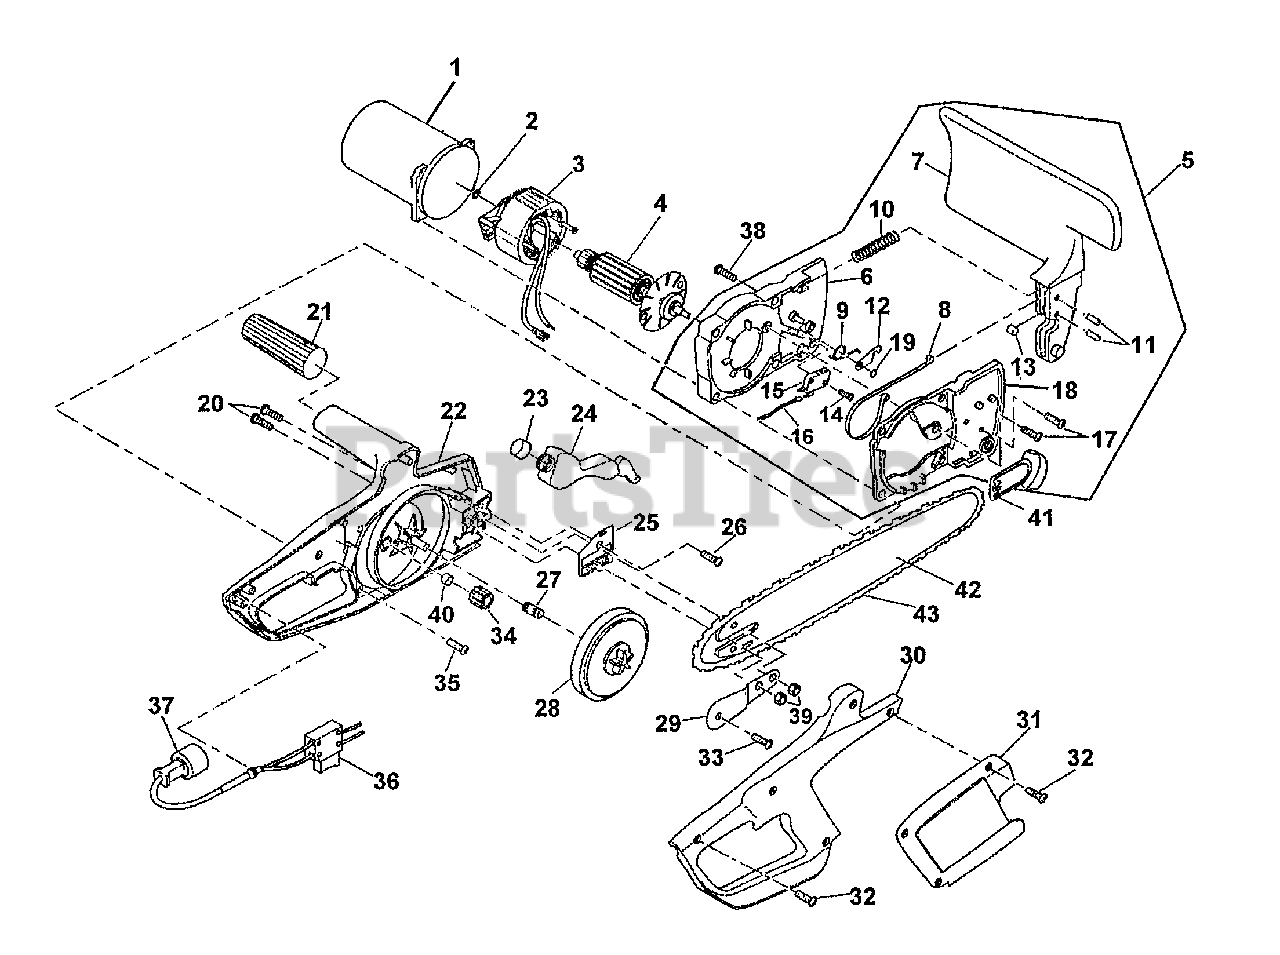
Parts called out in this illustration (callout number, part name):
1	CASE, MOTOR
2	WASHER, THRUST
3	FIELD
4	ARMATURE
5	CHAIN BRAKE ASSY
6	CASE, CHAIN BRAKE
7	GUARD, HAND
8	BAND, BRAKE
9	SPRING
10	SPRING, COMPRESSION
11	PIN, DOWEL
12	LATCH, BRAKE
13	BUSHING
14	SCREW 4-17×5/8"
16	WIRE ASSY
17	SCREW 10-32×7/8
18	COVER, CHAIN BRAKE
19	RING, RETAINING
20	BOLT - 1/4-20×1-3/8
21	GRIP, FOAM
22	HOUSING, GEAR CASE
23	CAP, OIL
24	TANK, OIL
25	PLATE ASSY, ADJUSTING
27	BEARING, SPROCKET
28	GEAR
29	SUPPORT, SPROCKET
30	COVER, SIDE
31	COVER, SPROCKET
33	SCREW
34	GEAR, DRIVE
35	SCREW 10-16×1-7/8
36	JOINT PACKING
37	CORD
38	SCREW 6-20×1-1/2"
39	NUT 1/4"-20
40	BEARING, NEEDLE
41	KICK GUARD
42	SAWING CHAIN - 12" -- XTRAGUARD
42	SAWING CHAIN - 91VG
43	GUIDE BAR - 12"
43	GUIDE BAR - 16"
